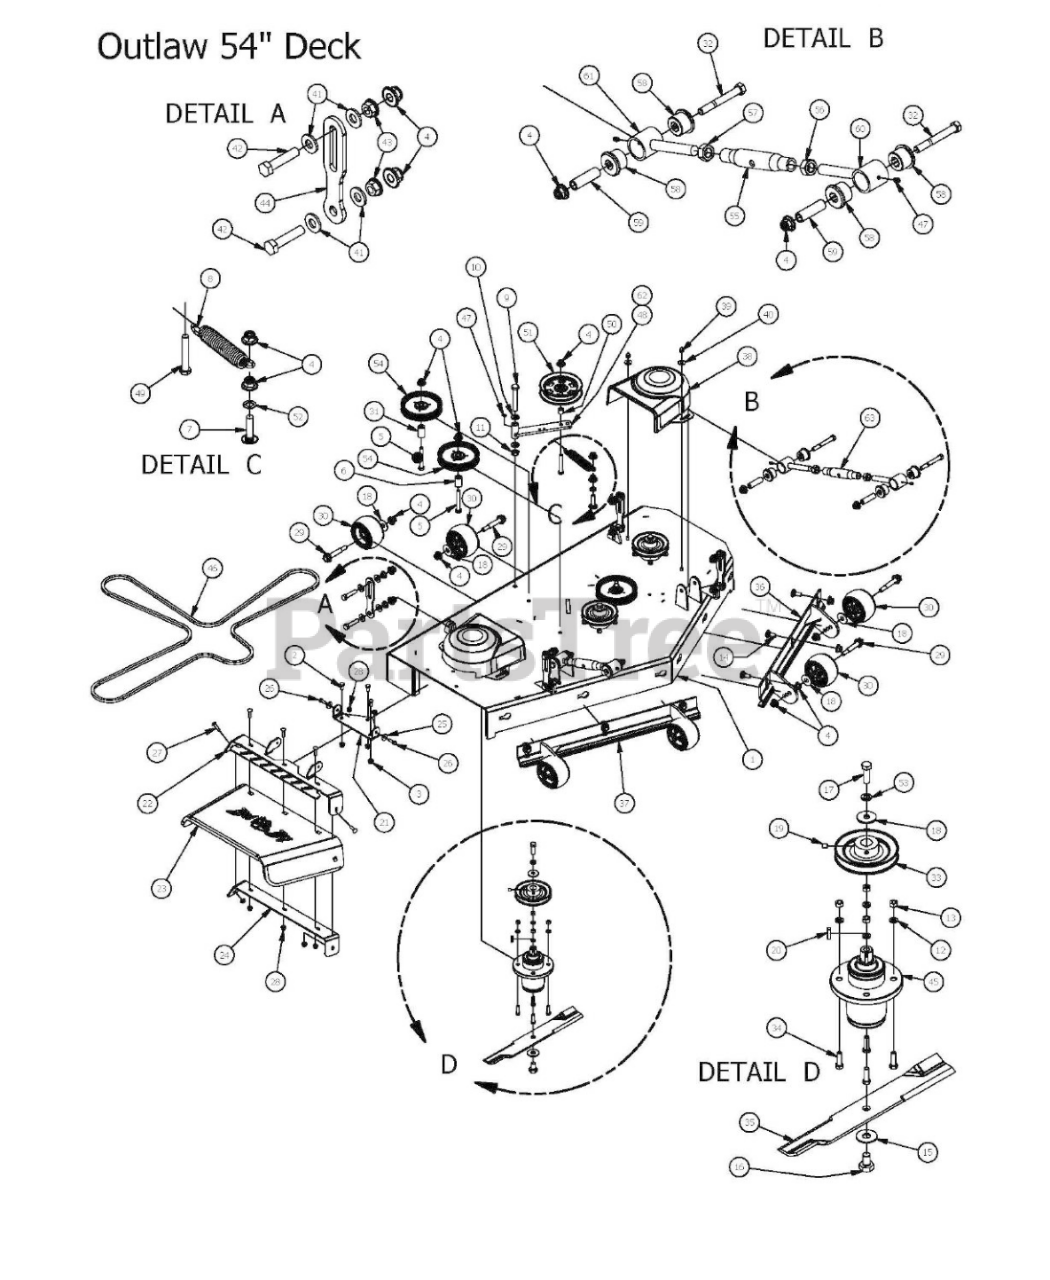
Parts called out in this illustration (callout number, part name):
1	2015 54" Deck
2	3/8" x 3/4" Hex Bolt
3	3/8" Flange Nut
4	1/2-13 Nylon Flange Nut
5	1/2 x 3 1/2 Flange Bolt Grade 8
6	Idler Pulley Standoff
7	1/2 x 2" Carriage Bolt
8	2015 Deck Idler Spring Outlaws
9	5/8" x 4" Hex Bolt
10	630 ID Plastic Washer
11	5/8-11 Nylon Insert Jam Half Nut
12	3/8 Lockwasher Zinc
13	3/8-16 Hex Nuts Zinc
14	1/2" x 1 1/4 Carriage Bolt
15	5/8" Flat Washer
16	5/8" x 1 1/2" Grade 8 Hex Bolt (Fine)
17	1/2"-20 x 1 1/2-Grade 5 Fine Thread Bolt
18	1/2" Belleville Washer
19	5/16 Set Screw
20	1/4" x 1" Key
21	Discharge Chute Hanger (deck mounted)
22	60" Discharge Chute Upper Hanger
23	Rubber Discharge Chute
24	60" Discharge Lower Bracket
25	360 ID Plastic Washer
26	5/16" x 1" Bolt
27	5/16" x 1 1/4" Carlage Bolt
28	5/16" Nylock Flange Nut Zinc
29	Deck Wheel Bolt
30	Anti-Scalp Roller
31	1 3/4" Pulley Spacer
32	1/2" x 4" Bolt (Grade 8)
33	5.25" Deck Spindle Pulley
34	3/8" x 1 1/4" Hex Bolt
35	54" Deck Fusion Blade For Outlaw
36	54 Deck Adustable Front (Left)
37	54 Deck Adustable Front (Right)
38	Pulley Cover
39	Acom nut-pulley Cover
40	360 ID Plastic Washer-Black
41	505 Nylon Spacer
42	1/2-13X 2-1/4 GR Hex Bolts.
43	1/2" Flange Nut
44	Deck Hanging Tab
45	OUTLAW SPINDLE ASSEMBLY
46	60" ZT Deck Belt
47	1/4" Press in Grease Fitting
48	Deck Idler
49	1/2-13 x GR 5 Hex Bolt Zinc
50	Spacer 3/4 00 x 1/2 ID x 34 Length
51	5 Idler Pully
52	517 Square Hole Round Washer
53	1/2" Lock Washer
54	5-3/4 Idler Pulley-Capitol Stampings
55	2015 Outlaw Toplink Body
56	3/4-10 Left-Handed Hex Nuts Zinc
57	3/4-10 Hex Nuts Zinc
60	Turn Left-Handed
61	Right-Handed End
62	Deck Idler Assembly - Includes parts: 4,47,48,50,51
63	Turnbuckle Assembly
